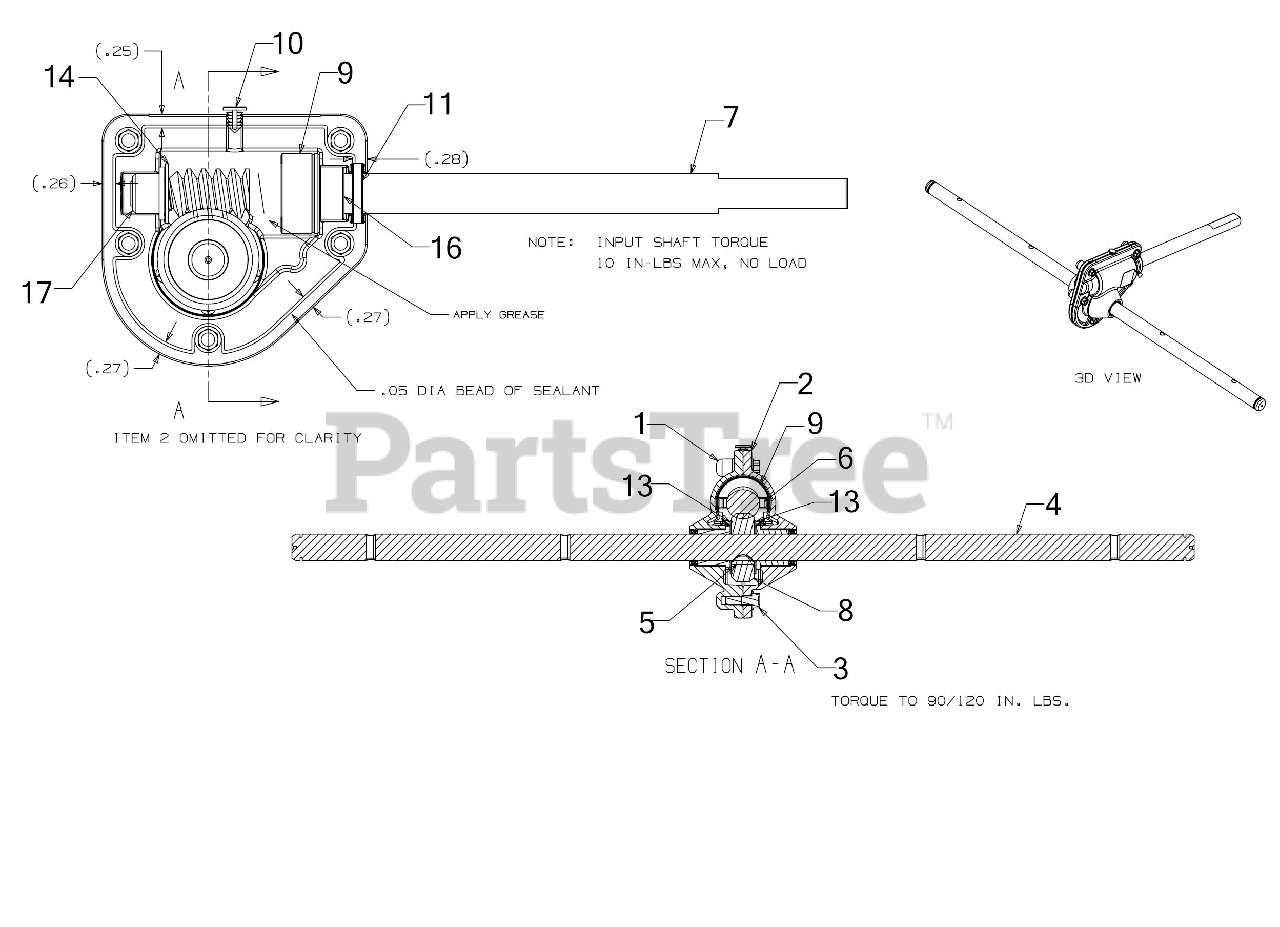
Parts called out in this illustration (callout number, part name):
1	REDUCER HOUSING ASSEMBLY (RH)
2	REDUCER HOUSING ASSEMBLY (LH)
3	SCREW 1/4-20 x .750
4	26" AUGER AXLE
5	KEY 3/16 x 5/8 H
7	WORM SHAFT
8	WORM GEAR 20T
9	COLLAR-THRUST .756ID x .600
11	OIL SEAL .75 x 1.131 x .188
13	THRUST WASHER
14	FLAT WASHER
16	FLANGE BEARING
17	FLANGE BEARING
